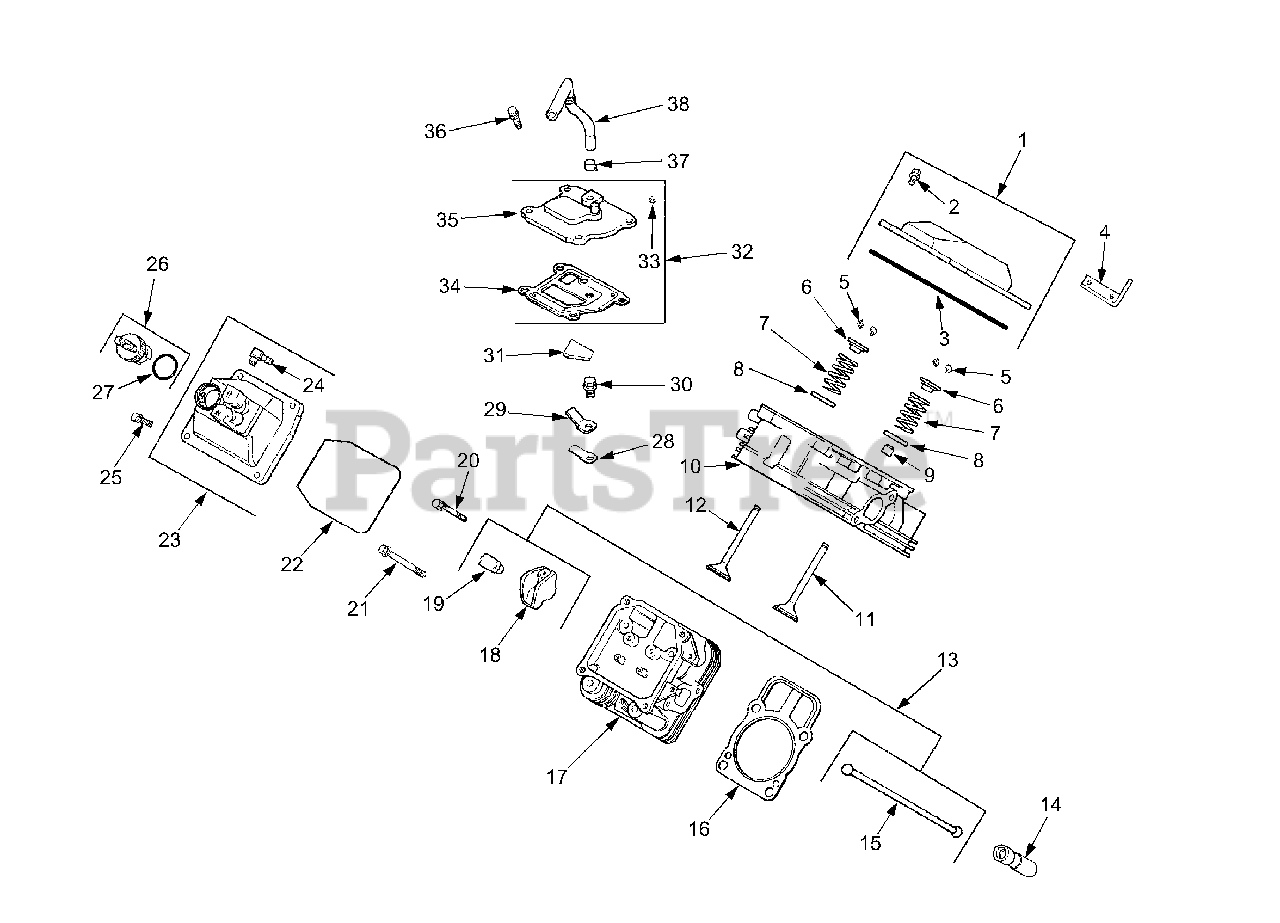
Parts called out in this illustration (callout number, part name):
1	Kit, Valve Cover
2	Screw, Shoulder
3	O-Ring, Valve Cover
4	Strap, Lifting
5	Kit, Retainer
6	Cap, Valve Spring
7	Spring, Valve
8	Retainer, Spring
9	Seal, Valve Stem.
10	Head Assembly, #1 Cylinder
11	Valve, Intake (Std.)
12	Valve, Exhaust (Std.)
13	Kit, Valve Train
14	Lifter, Valve
16	Gasket, Cylinder Head
17	Head Assembly, #2 Cylinder
19	Pivot, Rocker Arm
20	Screw, Hex Flange M6 x 1 x 34
21	Screw, Hex Flange M10 x 1.5 x 90
22	O-Ring, Valve Cover.
23	Cover, Fuel Pump Valve
24	Connector 90°.
25	Screw, Shoulder
26	Cap Assembly, Oil Fill
27	O-Ring
28	Reed, Breather
29	Retainer, Breather Reed
30	Screw, Hex Flange M5 x 0.8 x 10
31	Filter, Breather
32	Kit, Breather
33	Plug, Allen Head 1/8 NPTF
34	Gasket, Breather
35	Cover, Breather
36	Screw, Hex Flange M6 x 1.0 x 20
37	Clamp, Breather
38	Hose, Breather
